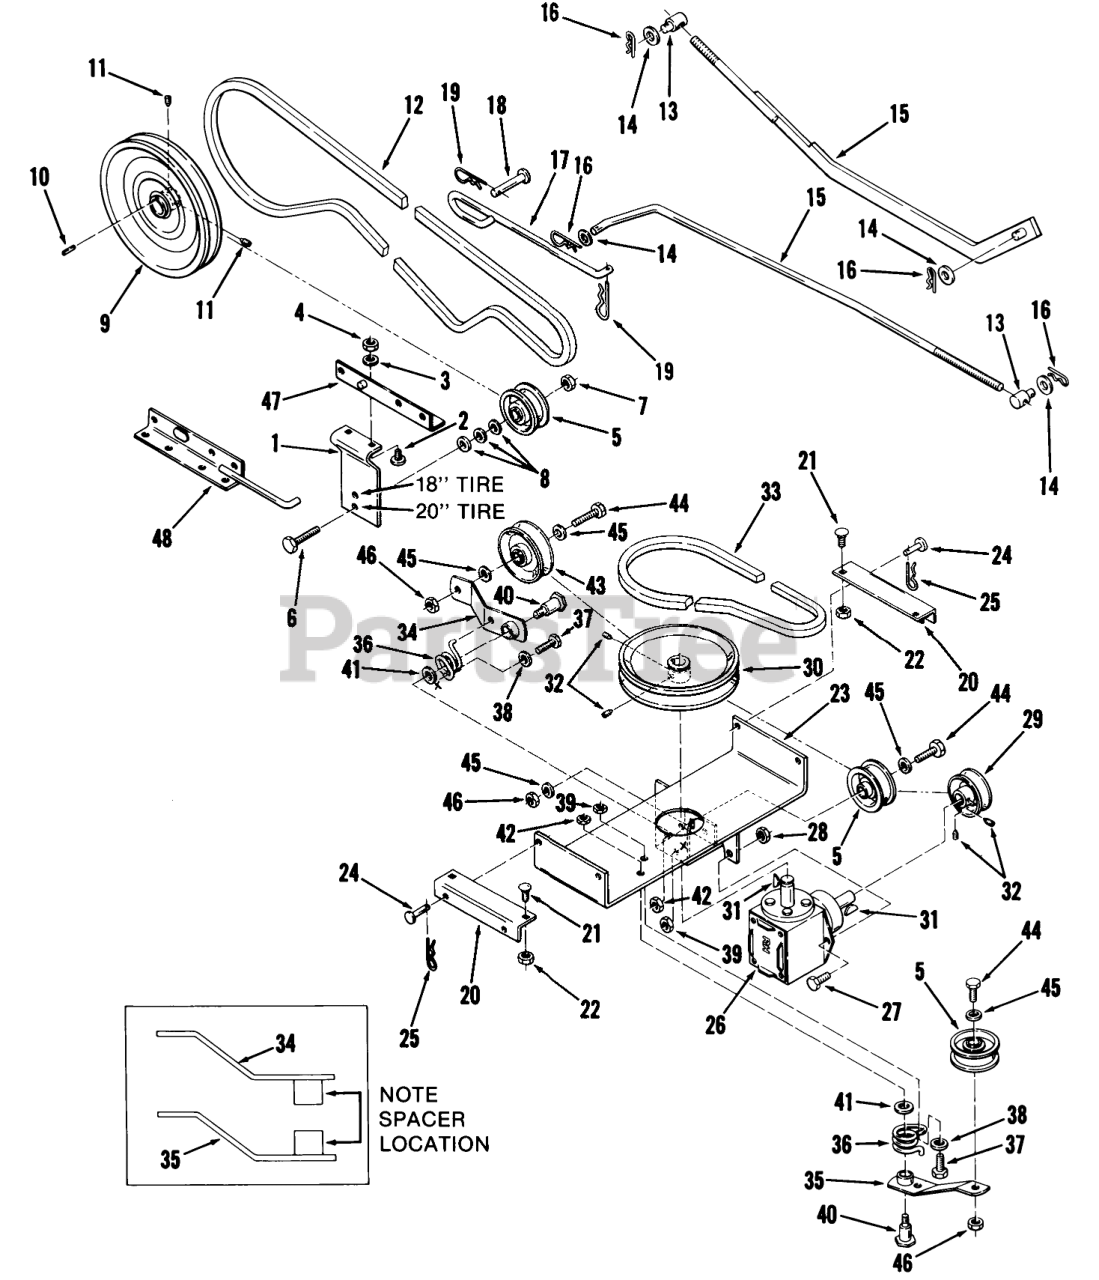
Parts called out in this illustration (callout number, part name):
1	Idler Bracket
2	Bolt
3	WASHER 5/16 SAE
4	Nut
5	Flat Idler
6	Bolt
7	Nut
8	Washer
9	Pulley
10	KEY-STRAIGHT
11	Set Screw 5/16-18 x 3/8
12	V-BELT
13	ROD-TRUNNION LIFT
14	Washer
15	Primary Lift Rod (5-SpeedTrans.) 07-30TL01 & 02
15	ASSY BAR LIFT R
16	Hairpin Cotter
17	Secondary Lift Rod
18	CLEVIS PIN
19	Hairpin Cotter
20	Quick Attach Plate
21	CARRIAGE BOLT -4
22	Nut
23	Support
24	PIN
25	Hairpin
26	Gearbox-RH (Peerless #1784-91)
27	BOLT
28	Nut
29	Pulley-Transmission Output 2.75 in. O.D.
30	Pulley-Transmission Input 8 in. O.D.
31	Key
32	Set Screw 5/16-18 x 3/8
33	V-BELT
34	Idler Arm-Output
35	ASSY-IDLER ARM R
36	SPRING-TORSION
37	BOLT
38	Washer
39	Nut
40	BOLT-SHOULDER
41	WASHER
42	Hex Nut 7/16-14
43	PULLEY-IDLER
44	Bolt
45	Washer
46	Nut
47	Hitch Support LH (5-Speed Trans.) 07-30TL01 Only
47	SUPPORT-HITCH ASSY LH R
48	Hitch Support RH (5-SpeedTrans.) 07-30TL01 Only
48	HITCH SUPPORT ASSY (RH)R
